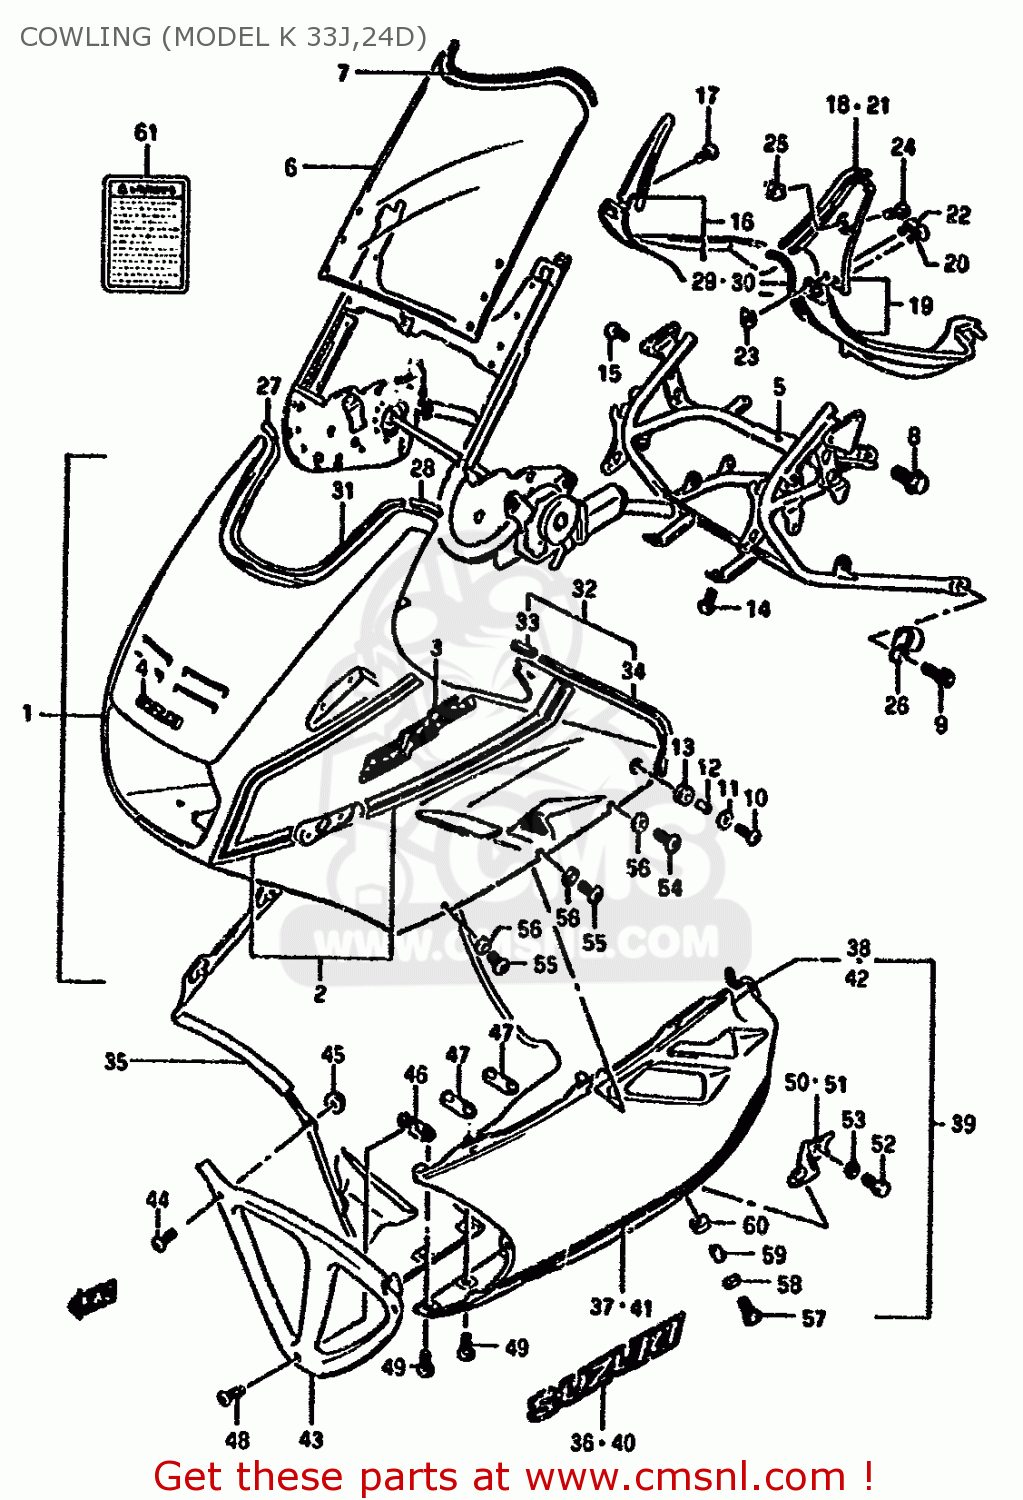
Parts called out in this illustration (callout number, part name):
1	BODY ASSY,COWLING (MAROON)
2	TAPE SET
3	EMBLEM (SPS)
4	EMBLEM,COWLING,UPPER
5	BRACE,COWLING
6	WINDSCREEN
7	MOLDING
8	BOLT(10X12)
9	BOLT
10	SCREW(6X20)
11	WASHER(6.5X18X1)
12	SPACER
13	CUSHION
14	SCREW(6X16)
15	SCREW 6X12
16	PANEL ASSY,R
17	SCREW
18	MOLDING,COWL.
19	PANEL ASSY,L
20	SCREW
21	MOLDING,COWL.
22	SCREW, FRONT & REAR
23	NUT
24	SCREW
25	NUT
26	CLAMP
27	CAP,PANEL & COWLING,R
28	CAP,PANEL & COWLING,L
29	MOLDING,COWLING PANEL,R
30	MOLDING,COWLING PANEL
31	MOULDING
32	MOLDING,COWLING BODY SIDE
33	COVER,MOLDING END
34	MOLDING,COWLING BODY SIDE
35	COVER ASSY,LOWER RH (MAROON)
36	EMBLEM
37	TAPE,RH
38	MOLDING,COWLING,LOWER
39	COVER ASSY,LOWER LH (MAROON)
40	EMBLEM
41	TAPE,LH
42	MOLDING,COWLING,LOWER
43	COVER,COWLING,LOWER,FRONT
44	SCREW(5X14)
45	NUT
46	BRACE,COWLING LWR COVER
47	BRACE,COWLING LWR COVER RR
48	SCREW(6X12)
49	SCREW(6X16)
50	BRACE,COWLING LWR,R
51	BRACE,COWLING LWR,L
52	BOLT 8X12
53	LOCK WASHER
54	SCREW(6X20)
55	SCREW(6X16)
56	WASHER
57	SCREW(6X20)
58	WASHER(6.5X18X1)
59	SPACER(6.4X9.2X12)
60	CUSHION
61	LABEL (WARNING SCREEN)
